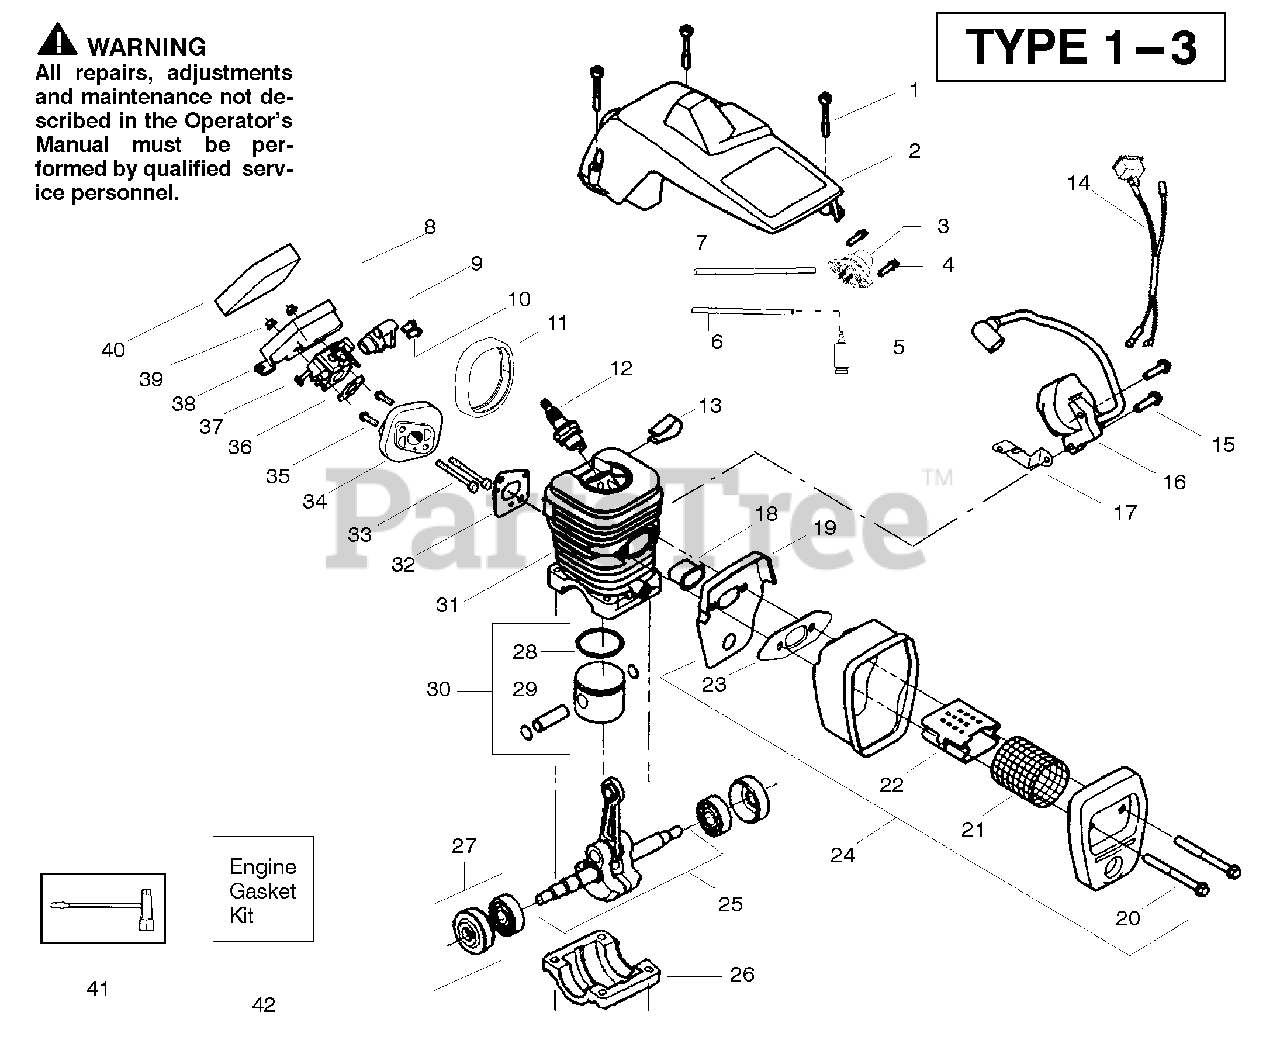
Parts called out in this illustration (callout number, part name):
2	Cylinder Shield
3	Air Purge Ass'y.
5	Fuel Pick-up Ass'y.
6	Kit-Line Purge/Carb. (Small Dia)
7	Kit-Line Purge/Tank (large line)
8	Grommet-Carb Adjust.
9	Limiter Cap-High
10	Limiter Cap-Low
11	Seal-Carb Adapter
12	Spark Plug (RCJ-7Y)
13	Clip-High Tension Lead
14	Wire Harness Ass'y
16	Ignition Module
17	Ground Strap
18	Heat Insulator
19	Muffler Back Plate
21	Spark Screen
22	Muffler Diffuser
23	Muffler Gasket
24	Muffler Ass'y
25	Crankshaft Assy.
26	Cap-Crankcase
27	Seal & Bearing Assy.
28	Piston Ring
29	Retainer - Piston Pin
30	Piston Kit
31	Cylinder Kit
32	Gasket - Carb. Adapter
34	Carb. Adapter Kit
36	Carb. Gasket
37	Carburetor Kit
38	Air Filter Housing
39	Nut - Carb. Screw
40	Air Filter - Foam
41	Scrench
42	Engine Gasket Kit
